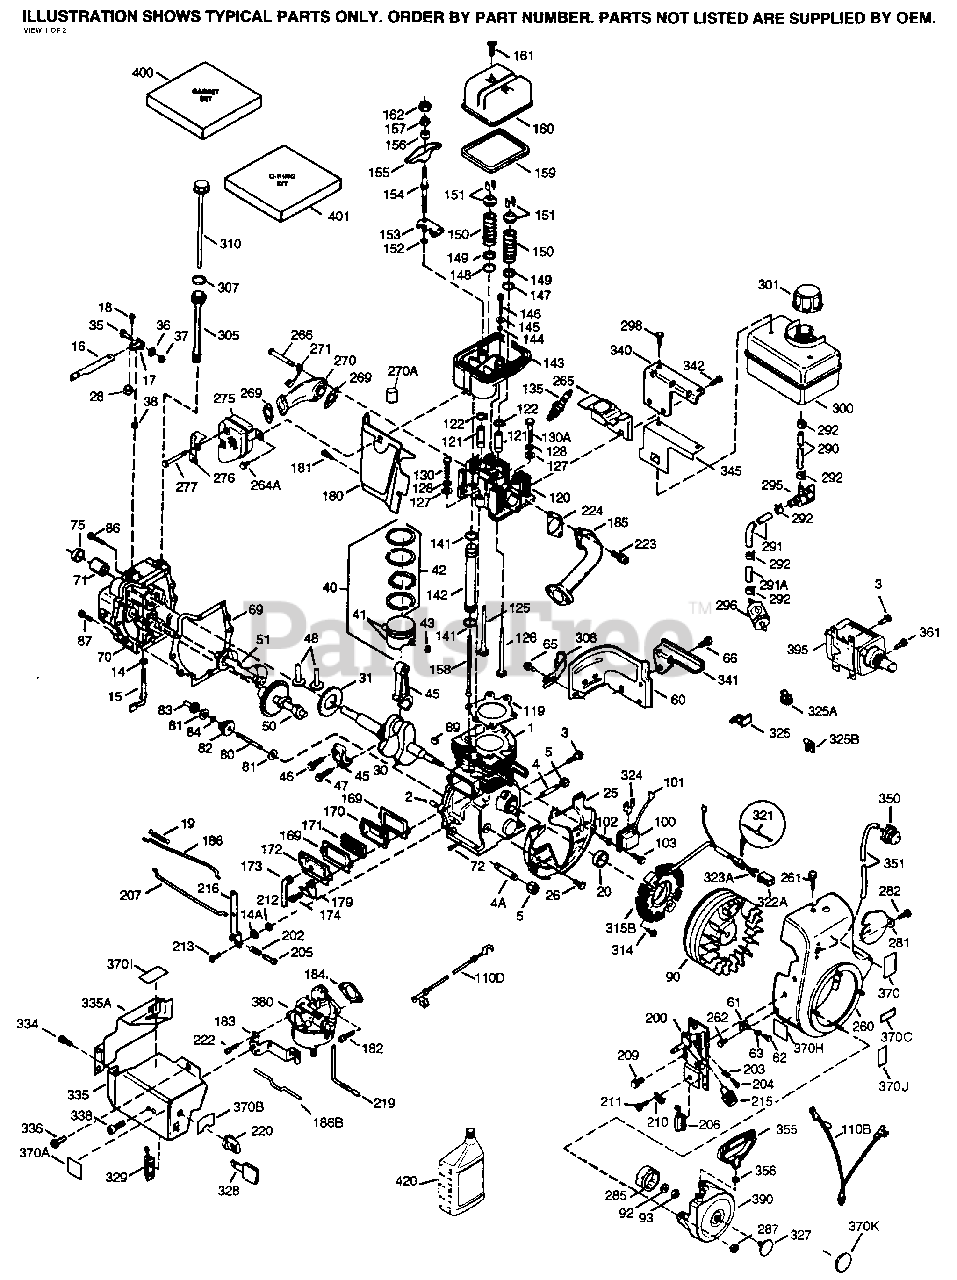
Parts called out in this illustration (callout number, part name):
1	"Cylinder (Incl. 2, 20, 72 & 80)
2	Dowel Pin
3	Screw, 1/4-20 x 1/2"
4	Oil Drain Extension
5	Extension Cap
14	Flat Washer
15	Governor Rod (Incl. 14 & 38)
16	Governor Lever
17	Governor Lever Clamp
18	Screw, 8-32 x 5/16"
19	Extension Spring
20	Oil Seal
25	Blower Housing Baffle
26	Screw, 1/4-20 x 5/8"
28	Lock Nut, 8-32
30	Crankshaft
31	Counterbalance Gear
35	Screw, 10-32 x 3/4"
36	Lock Washer #8
37	Lock Nut, 10-32
38	Retaining Ring
40	Piston, Pin & Ring Set (Std.)
40	Piston, Pin & Ring Set (.010" OS)
40	Piston, Pin & Ring Set (.020" OS)
41	Piston & Pin Ass'y. (Std.) (Incl. 43)
41	Piston & Pin Ass'y. (.010" OS) Incl. 43
41	Piston & Pin Ass'y. (.020" OS) Incl. 43
42	Ring Set (Std.) (3-5/16")
42	Ring Set (.010" OS)
42	Ring Set (.020" OS)
43	Piston Pin Retaining Ring
45	Connecting Rod Ass'y. (Incl.46,47,49)
46	Connecting Rod Bolt
47	Connecting Rod Bolt
48	Valve Lifter
50	Camshaft (MCR)
51	Counterbalance Weight
60	Blower Housing Extension
61	Grommet Mounting Bracket
62	Screw, 8-32 x 3/8"
63	Breather Tube Grommet
64	Screw, T-30, 1/4-20 x 1/2"
65	Screw, 10-24 x 1/2"
66	Screw, 1/4-20 x 5/8"
69	* Cylinder Cover Gasket
70	Cylinder Cover (Incl. 14, 15, 38, 71 & 75)
71	Crankshaft Bushing
72	Oil Drain Plug (Sq. hd., 1/4-18)
75	Oil Seal
80	Governor Shaft
81	WASHER
82	Governor Gear Assembly
83	Governor Spool
84	Retaining Ring
86	Screw, 1/4-20 x 1-3/16"
87	Screw, 1/4-20 x 1-11/16"
89	Flywheel Key
90	Flywheel (W/Ring Gear)
92	Lock Washer
93	Flywheel Nut
100	Solid State Ignition
101	Spark Plug Cover
102	Solid State Mounting Stud
103	Screw, Torx T-15, 10-24 x 1"
119	* Cylinder Head Gasket
120	Cylinder Head
121	Valve Guide Kit (Incl. 2 of 122)
122	Retaining Ring
125	Exhaust Valve (Std.)
125	Exhaust Valve (1/32" OS)
126	Intake Valve (Std.)
126	Intake Valve (1/32" OS)
128	Belleville Washer
130	Screw, 5/16-18 x 1-3/4"
130A	Screw, 5/16-18 x 1-3/8"
135	Resistor Spark Plug (RL86C)
141	* "O" Ring (Also Incl. in 401)
142	Push Rod Tube
143	Rocker Arm Housing
144	* "O" Ring (Also Incl. in 401)
146	Screw, 1/4-20 x 29/32"
147	* "O" Ring (Also Incl. in 401)
148	* "O" Ring (Also Incl. in 401)
149	Valve Spring Cap
150	Valve Spring
151	Valve Spring Keeper
152	* "O" Ring (Also Incl. in 401)
153	Push Rod Guide
154	Rocker Arm Stud
155	Rocker Arm
156	Rocker Arm Bearing
157	* Lock Nut (Incl. 162) Also Incl. in 4 01
158	Push Rod
159	* "O" Ring (Incl. 2 of 161) Also Incl. in 401
160	Rocker Arm Housing
161	Screw, Torx T-20, 8-32 x 1/2"
162	Jam Nut
169	* Valve Cover Gasket
170	Breather Body
171	Breather Element
172	Valve Cover
173	Breather Tube
174	Screw, 10-24 x 1/2"
179	Retaining Clip
180	Blower Housing Extension
181	Screw, 10-24 x 1/2"
182	Screw, 1/4-20 x 27/32"
183	Choke Bracket
184	* Carburetor To Intake Pipe Gasket
185	Intake Pipe
186	Governor Link
200	Manual Control Bracket (Incl. 203, 20 4 & 206) & 211)
202	Compression Spring
203	Compression Spring
204	Screw, 5-40 x 7/16"
205	Screw, 6-32 x 21/32"
206	Terminal
207	Throttle Link
209	Screw, 10-32 x 1/2"
212	Bushing
215	Control Knob
216	R.P.M. Adjusting Lever
219	Choke Rod
220	Control Knob
222	Screw, 10-32 x 1/2"
223	Screw, 5/16-18 x 7/8"
224	* Intake Pipe Gasket
260	Blower Housing
261	Screw, T-30, 1/4-20 x 1/2"
262	Screw, T-40, 5/16-24 x 21/32"
265	Cylinder Head Cover
266	Screw, 5/16-18 x 1-1/4"
269	* Exhaust Manifold Gasket
270	Exhaust Manifold
271	Locking Plate (Manifold)
275	Muffler
276	Locking Plate
277	Screw, 5/16-18 x 4-1/2"
281	Starter Bubble Cover
282	Screw, 8-32 x 3/8"
285	Cup, Starter
287	Nut & Lock Washer 1/4-28
290	Fuel Line
291	Fuel Line (8.62")
292	Fuel Line Clamp
295	Fuel Shut-Off Valve
298	Screw, 1/4-15 x 3/4"
300	Fuel Tank (Incl. 292 & 301)
301	Fuel Cap (Red)
305	Oil Fill Tube
307	"O" Ring
308	Fill Tube Clip
310	Dipstick
314	Screw, 1/4-20 x 3/4"
327	Starter Plug
328	Ignition Key (also available in Packa ged Part #740077)
329	Terminal
334	Screw, 8-32 x 5/16"
335	Carburetor Cover
335A	Carburetor Cover
336	Screw, 10-32 x 1/2"
338	Screw, 10-32 x 1/2"
340	Fuel Tank Bracket
341	Fuel Tank Bracket
342	Screw, 5/16-18 x 7/8"
345	Heat Baffle
350	Primer Ass'y.
351	Primer Line
355	Starter Handle (Mitten Grip) also ava ilable in Packaged Part #740053B
370	Instruction Decal
370A	Choke Decal
370B	Primer Decal
370C	Warning Decal
370E	Speed Control Decal
380	Carburetor (Incl. 184)
390	Rewind Starter
400	Gasket Set notes) Incl. part #'s 2727 2A (1), 27896A (2), 28264 (2), 33263 (1), 33481 (4), 33484 (1), 33509 (1), 33515A (1), 33629 (2), 34410 (1), 34 912 (1), 35295 (2), 35299B (1), 35306 A (1), 35317 (1), 35683 (1), 35762 (2 )
401	"O'' Ring Kit (Also incl. in 400) 282 64 (2), 33481 (4), 33484 (1), 33509 ( 1), 34410 (1), 35295 (2), 35299B (1)
420	SAE 5W30 4-Cycle Engine Oil - Quart - Winter
